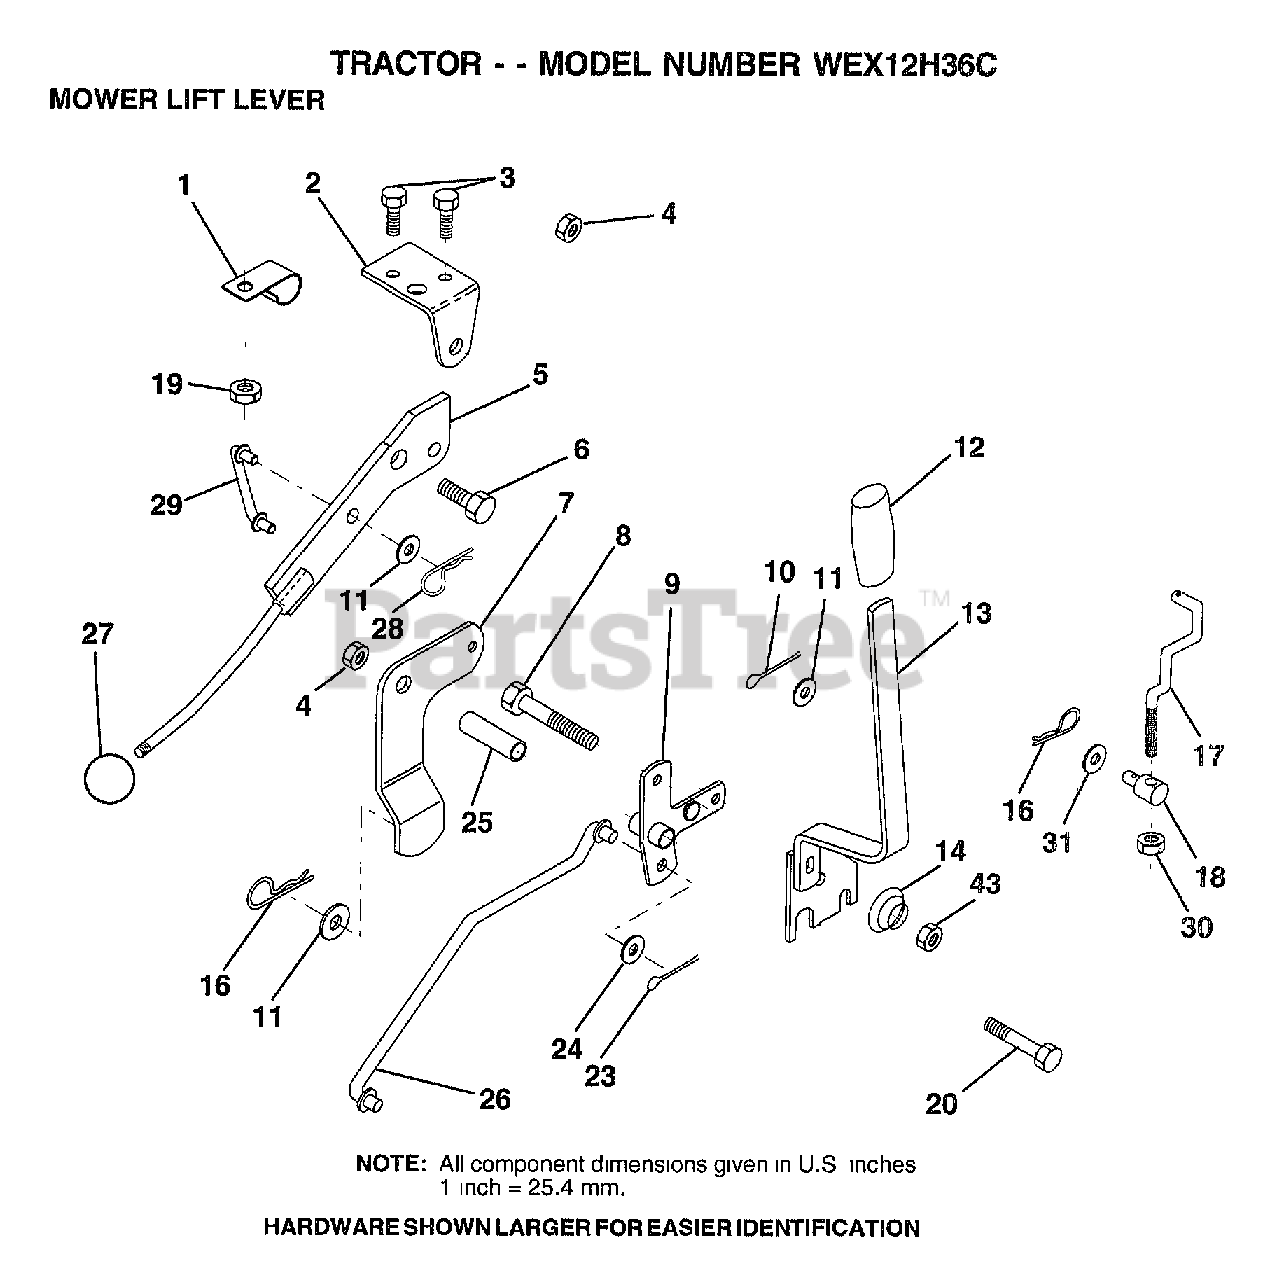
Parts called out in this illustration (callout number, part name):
1	"CLIP,INSULATOR"
2	BRKT CLUTCH
3	BOLT HXHD FIN
5	LEVER.ASM.CLUTCH
6	"BOLT, SHOULDER LT"
7	MWR CLUTCH ARM AS
8	BOLT
9	"BELLCRANK,LIFT"
10	COTTER PIN
11	WASHER
13	HANDLE.ASM.LIFT
14	SPRING COMPRESSIO
16	SPRING.RETAINER
17	"LINK,LIFT FRT"
18	TRUNION ADJ
20	BOLT
23	PIN COTTER 1/8
25	TUBE SPACER
26	ROD LIFT MOWER
27	KNOB T(3/8 HOLE)
28	RETAINER M
29	CLUTCH LINK
30	NUT
31	WASHER
